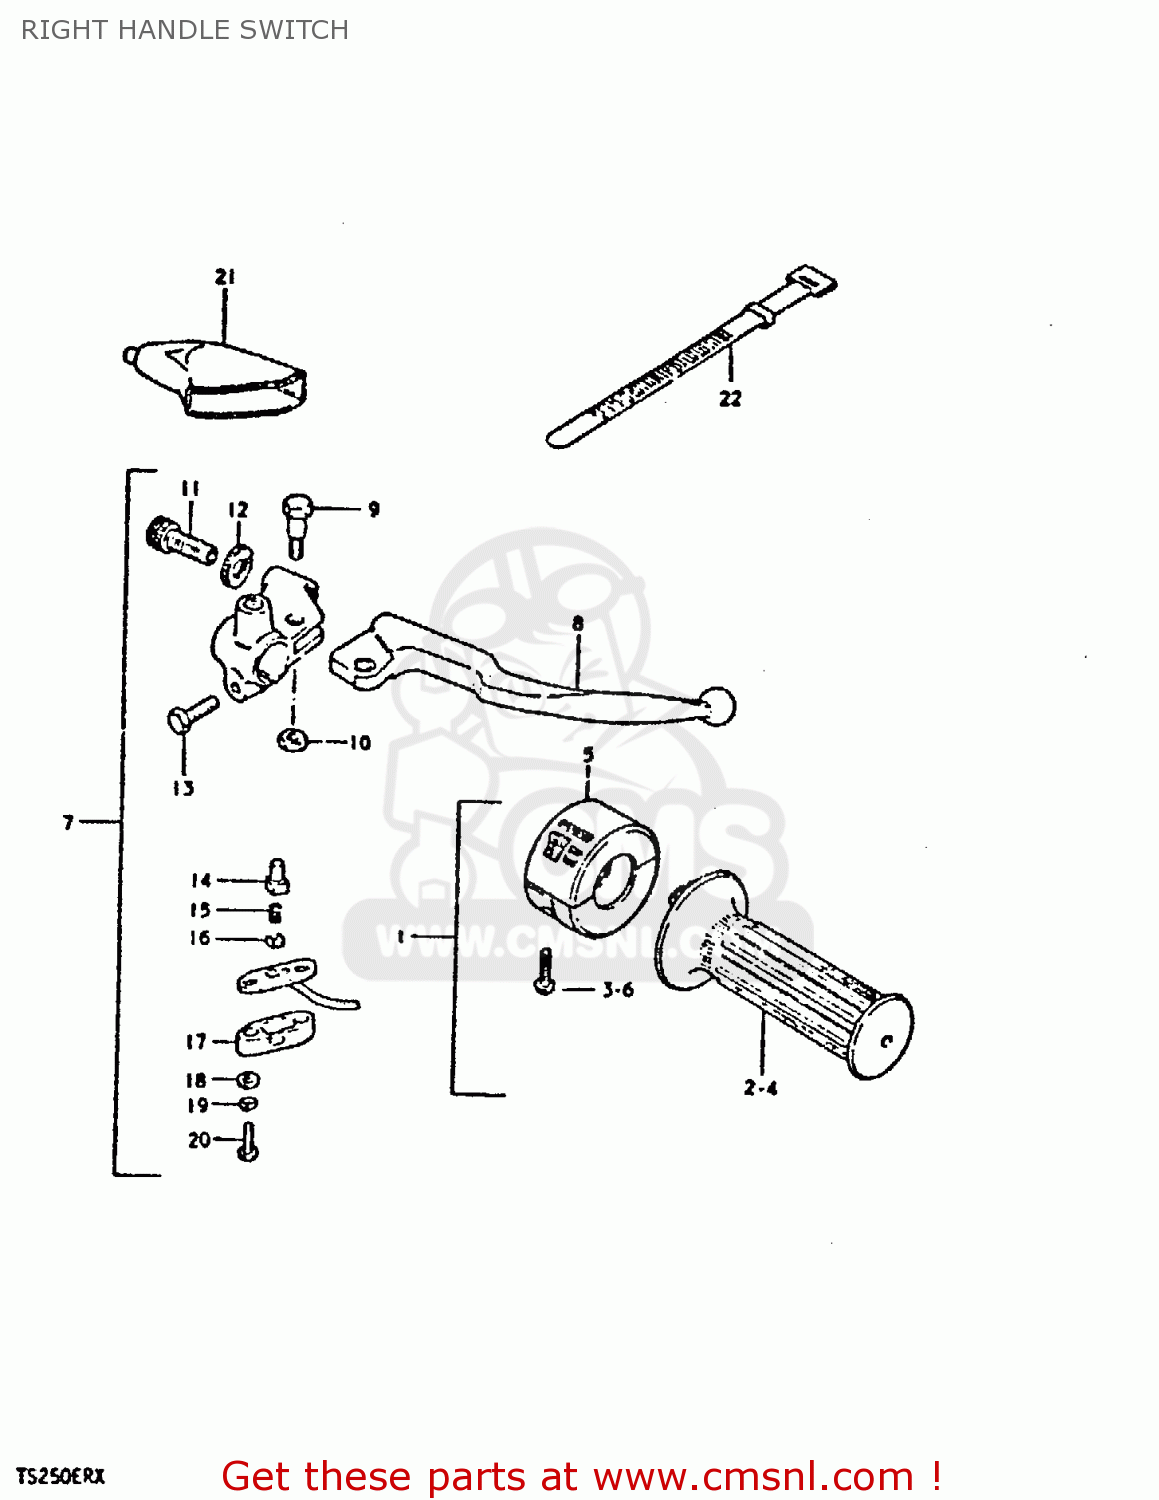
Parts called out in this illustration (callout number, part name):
1	CASE ASSEMBLY,THROTTLE
2	GRIP,THROTTLE
3	SCREW
4	GRIP,THROTTLE
5	CASE ASSEMBLY,THROTTLE
6	SCREW
7	LEVER/SWITCH ASSEMBLY,BRAKE
8	LEVER,BRAKE
9	BOLT,LEVER
10	NUT 6MM
11	ADJUSTER,CABLE
12	NUT,CABLE ADJUSTER
13	BOLT
21	COVER,CLUTCH LEVER
22	CLAMP(L:120)
